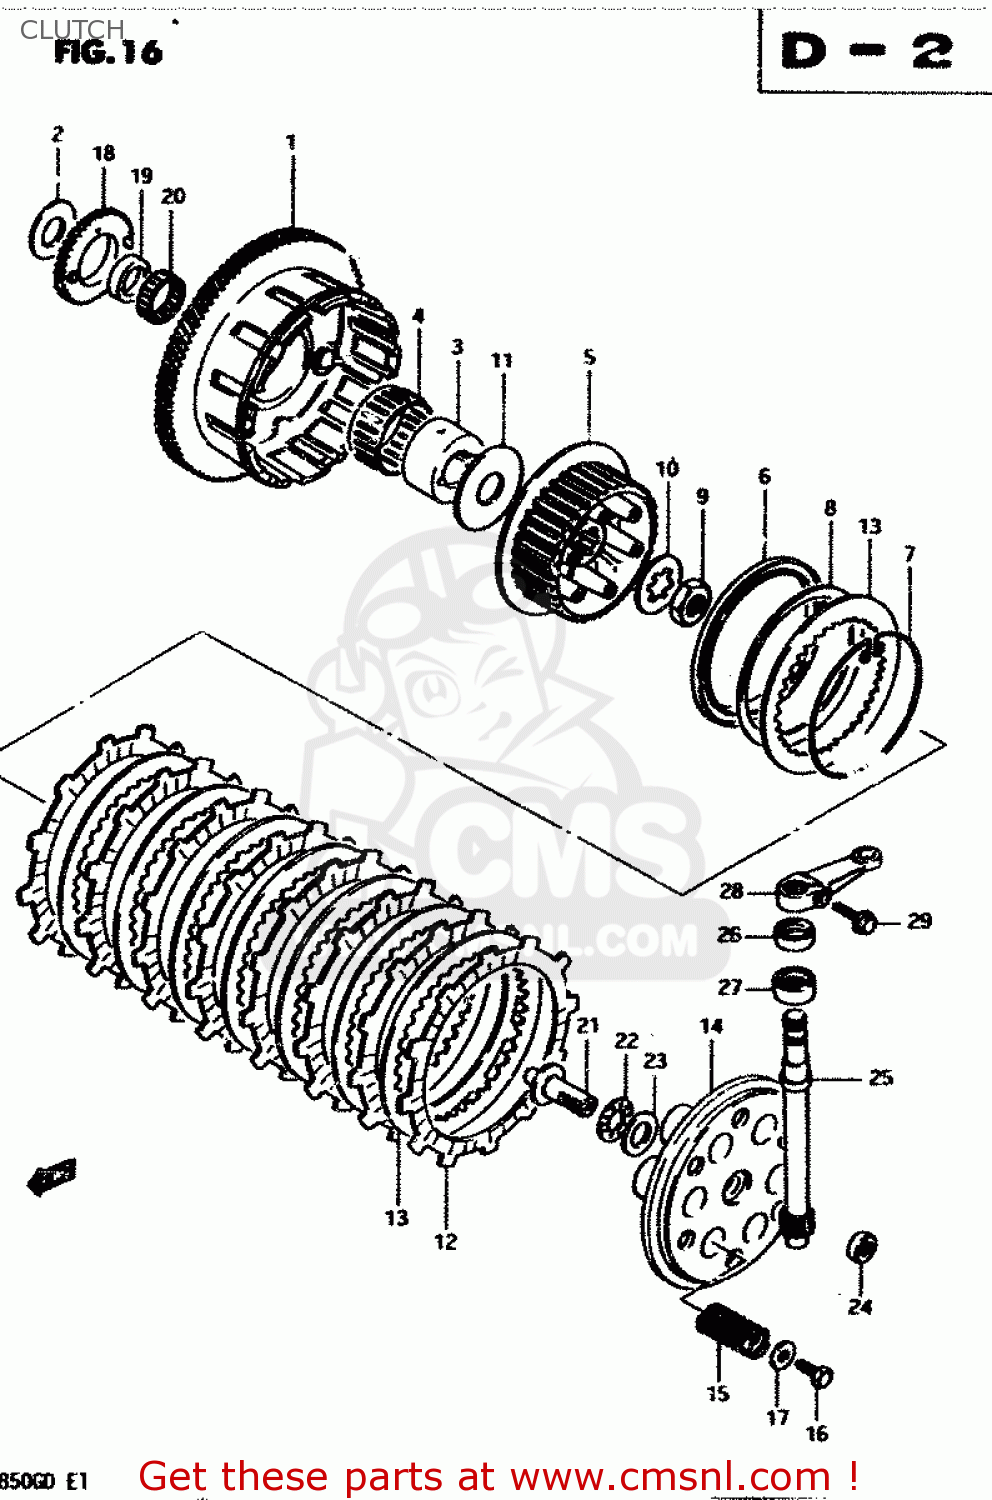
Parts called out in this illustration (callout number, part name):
1	GEAR ASSEMBLY,PRIMARY DRIVE
2	WASHER
3	SPACER,PRIMARY DRIVEN
4	BEARING
5	HUB,CLUTCH SLEEVE
6	SEAT,WAVE WASHER
7	RING,STOPPER
8	WASHER
9	NUT
10	WASHER,LOCK
11	WASHER(25X66X3.5)
12	PLATE,CLUTCH DRIVE (MCA)
13	PLATE,CLUTCH DRIVEN(T:2.0) (NAS)
14	DISC,CLUTCH PRESSURE
15	SPRING
16	BOLT, UPPER
17	WASHER
18	GEAR,ENG OIL PUMP DRIVE(NT:34)
19	SPACER,OIL PUMP DRIVE GEAR
20	BEARING(36X40X10)
21	RACK,CLUTCH RELEASE
22	BEARING(15X28X2)
23	WASHER
24	SEAL,OIL(10X16X5)
25	PINION,CLUTCH RELEASE
26	OIL SEAL
27	BEARING(15X22X12)
28	ARM,CLUTCH RELEASE
29	BOLT,REAR
